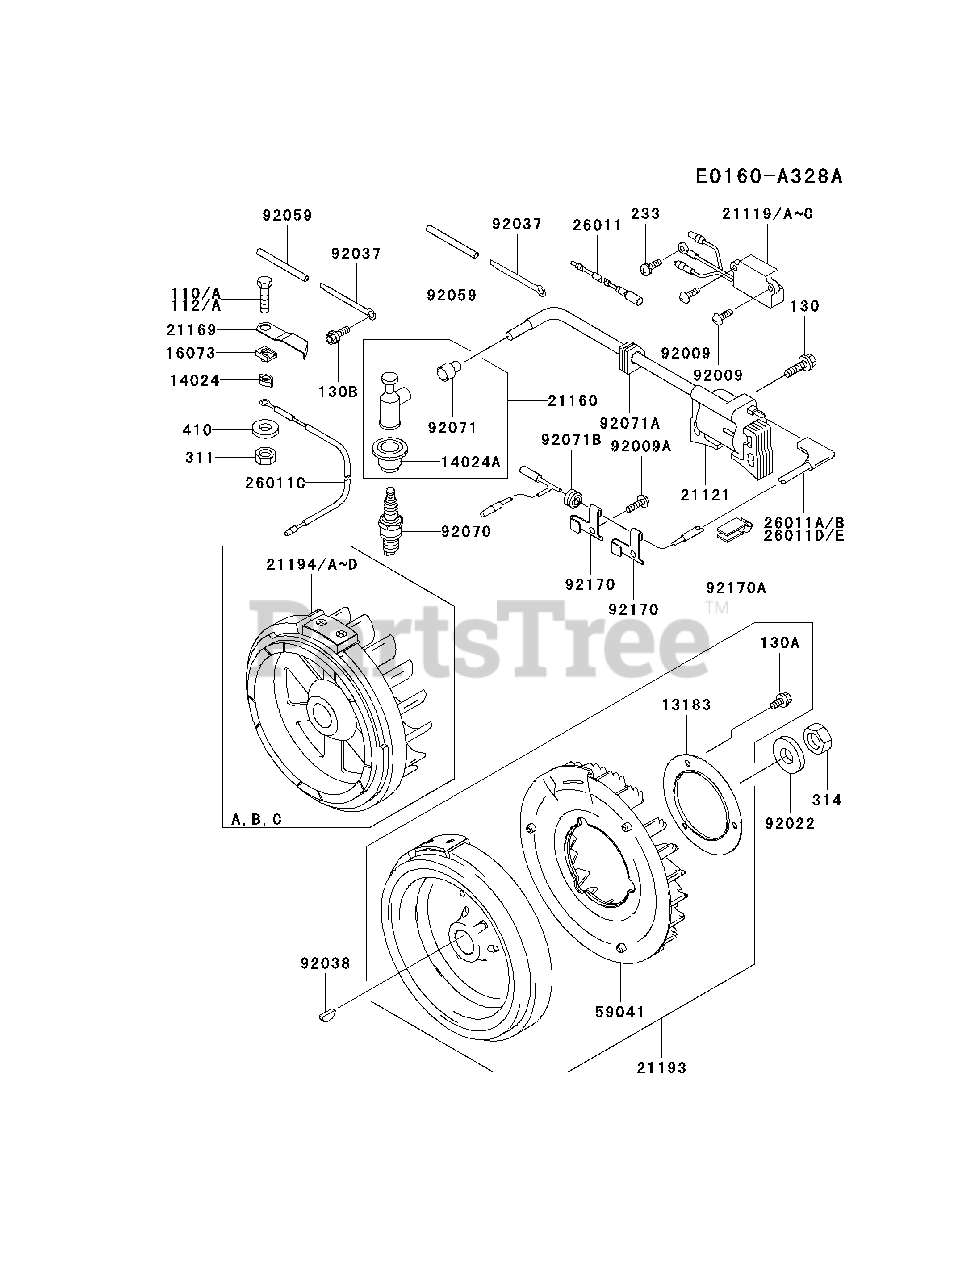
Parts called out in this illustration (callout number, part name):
110A	BOLT-FLANGED
112A	BOLT-UPSET
130	BOLT-FLANGED
130B	BOLT-FLANGED
233	SCREW-PAN-WP+-
311	NUT-HEX
314	NUT-HEX-FINE
410	W-PLAIN-S
